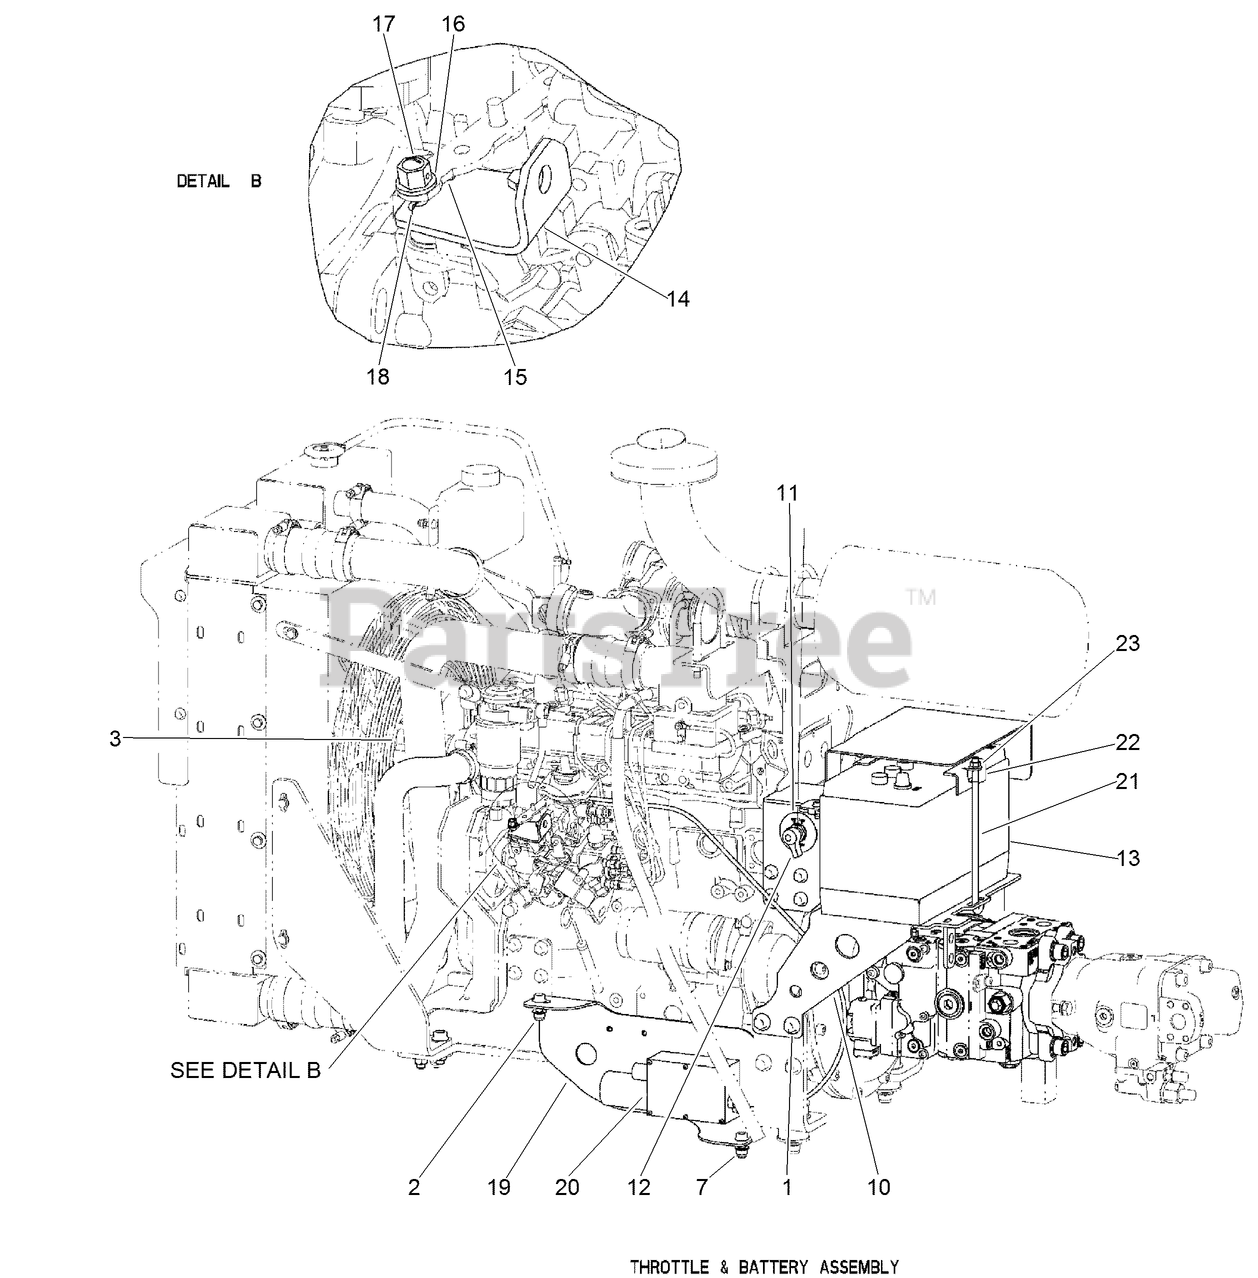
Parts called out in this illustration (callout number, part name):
1	SCREW, METRIC FLANGE w/BODY-M12 x 30
2	SCREW-HH
3	SCREW-FLANGE, METRIC
7	NUT-FLANGE, NYLOCK
10	ASSEMBLY - Battery Mount
11	FACEPLATE-BATTERY, ON/OFF
12	SWITCH-BATTERY (1000 AMP)
13	BATTERY - 12VDC
14	BRACKET - Throttle
15	BOLT - Thd to Hd M6 x 12 GR8 ZND
16	WASHER-FLAT
17	NUT - Cable Retaining
18	PIN - Cotter .062 x 1.00 in ZN
19	BRACKET - Throttle
20	ACTUATOR-THROTTLE
21	BOLT-HOLDDOWN, BATTERY
22	ANGLE-HOLDDOWN, BATTERY
23	NUT-Serr Flg 3/8-16 UNC GR5 ZND
